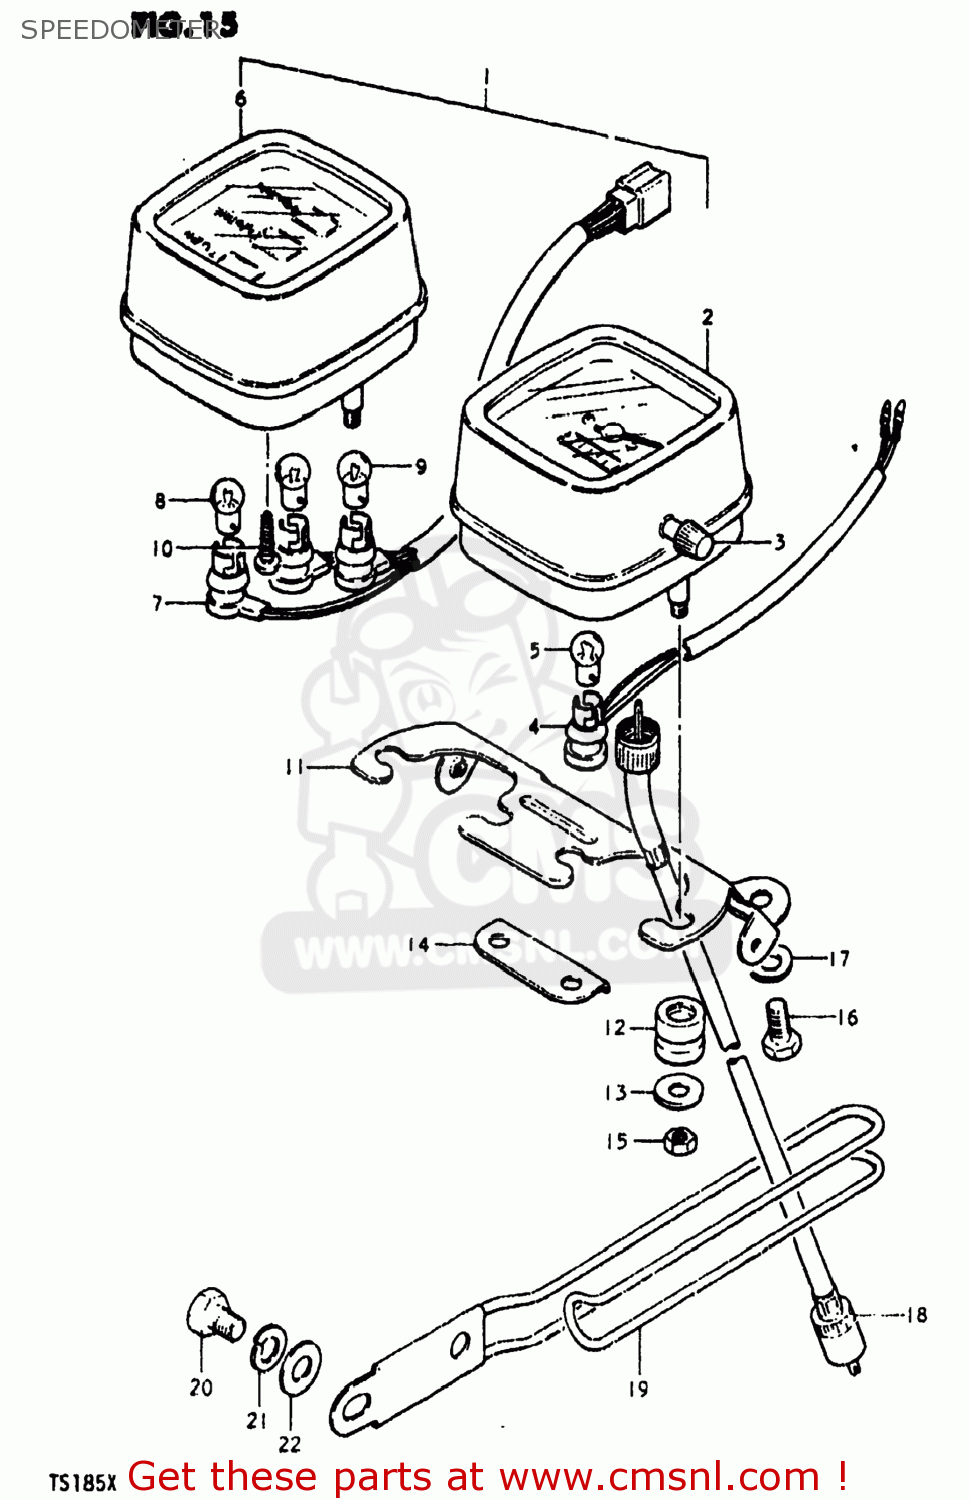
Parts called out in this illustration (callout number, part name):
1	SPEEDOMETER ASSEMBLY
2	SPEEDOMETER ASSEMBLY
3	KNOB,TRIP METER
4	SOCKET,SPEEDOMETER
5	BULB(6V/3W)
6	CASE,PILOT BULB
7	SOCKET
8	BULB(6V/3W)
9	BULB(6V1.7W,STANLEY,A61A)
10	SCREW
11	BRACKET,SPEEDOMETER
12	CUSHION
13	WASHER,METER
14	PLATE,METER CONNECTING
15	NUT
16	BOLT, UPPER
17	WASHER
18	CABLE ASSEMBLY,SPEEDOMETER
19	GUIDE,CABLE
20	BOLT 8X12
21	LOCK WASHER
22	WASHER
